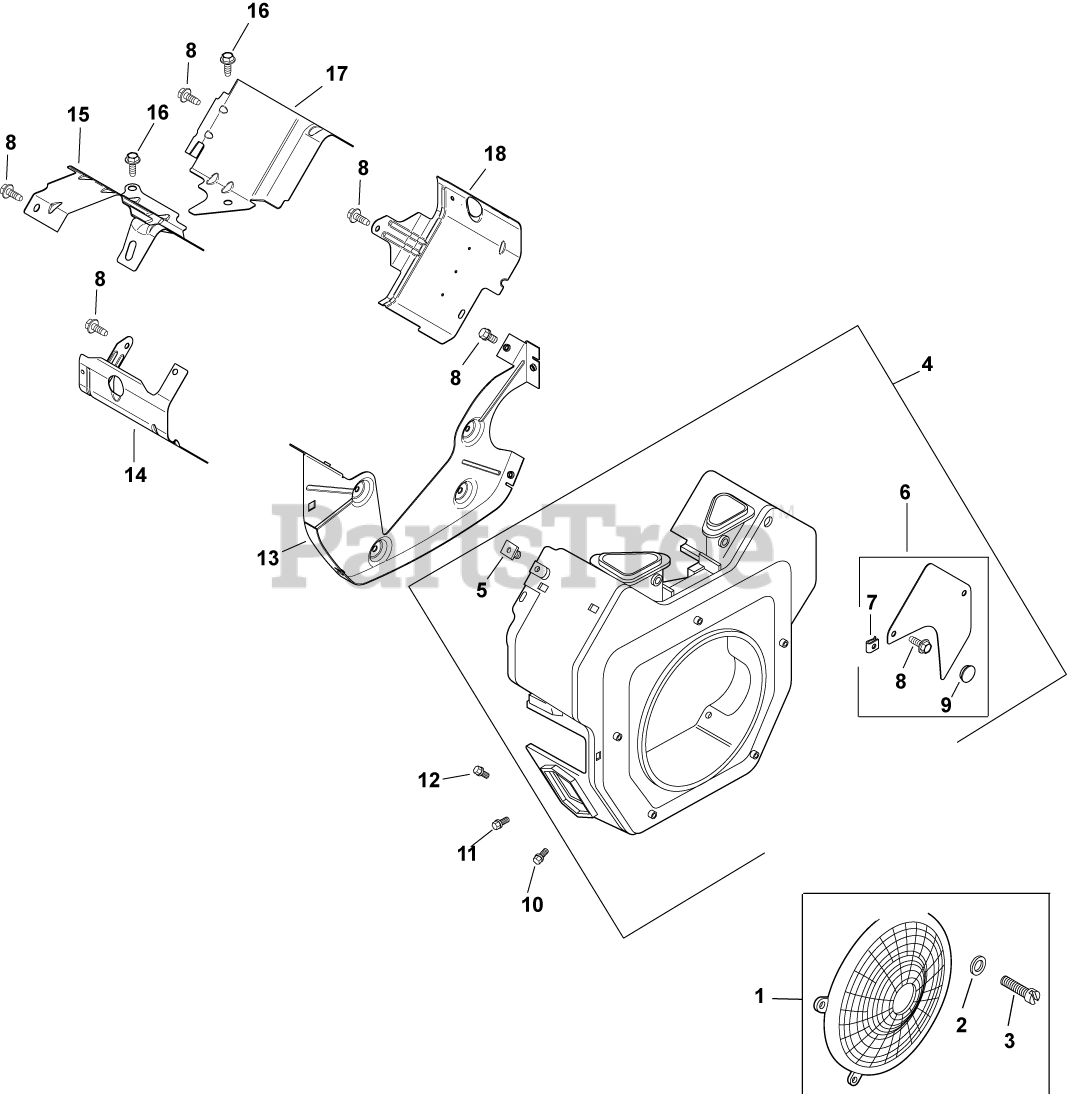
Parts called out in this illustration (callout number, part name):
1	KIT, FIXED GUARD
2	WASHER, FLAT 7/32"
3	SCREW, LBD SCKT PAN M5X0.8X10
4	KIT, BLOWER HOUSING ASSEMBLY
5	NUT, PLASTIC
6	KIT, ACCESS PANEL
7	CLIP, MOUNTING-USE 25 154 13-S
8	SCREW,FLG THD FRM M6X1.0X16-(#25086397S)
9	PLUG, BUTTON 9/16
10	SCREW,FLG THD FRM M5X0.8X16-(#25086398S)
11	SCREW - USE M-545016-S
12	SCREW, FLG THD FRM M5X.8X20-(#25086399S)
13	PLATE, BACKING-USE 24 146 59-S
14	BAFFLE, LEFT BARREL -USE 24 063 88-S
15	BAFFLE, VALLEY #2 SIDE-USE 24 063 94-S
16	SCREW, FLG THD FRM M5X.8X10
17	BAFFLE, VALLEY (CH)-USE 24 063 93-S
18	BAFFLE, RIGHT BARREL-USE 24 063 85-S
